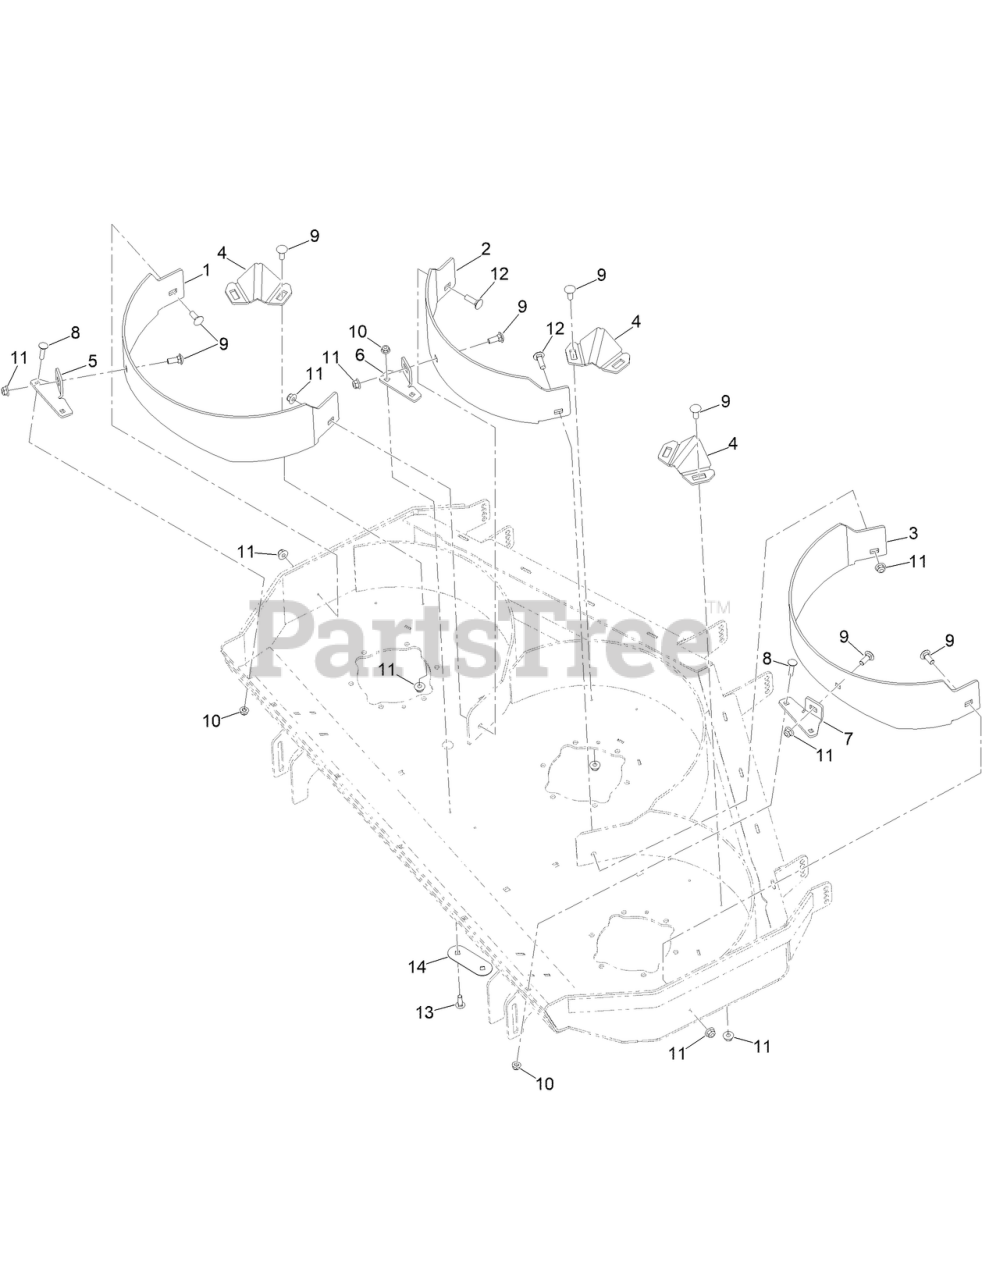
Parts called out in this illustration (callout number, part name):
1	BAFFLE-RECYCLER, RH
2	BAFFLE-RECYCLER, CTR
3	BAFFLE-RECYCLER, LH
5	BAFFLE-SUPPORT, RH
6	SUPPORT, CTR BAFFLE (RD)
7	BAFFLE-SUPPORT, LH
8	SCREW-CARR
9	BOLT-CARR
10	NUT-HF, NI
11	NUT-HF, NI
12	BOLT-CARR
13	SCREW-CARR
14	SHIM-PLATE
